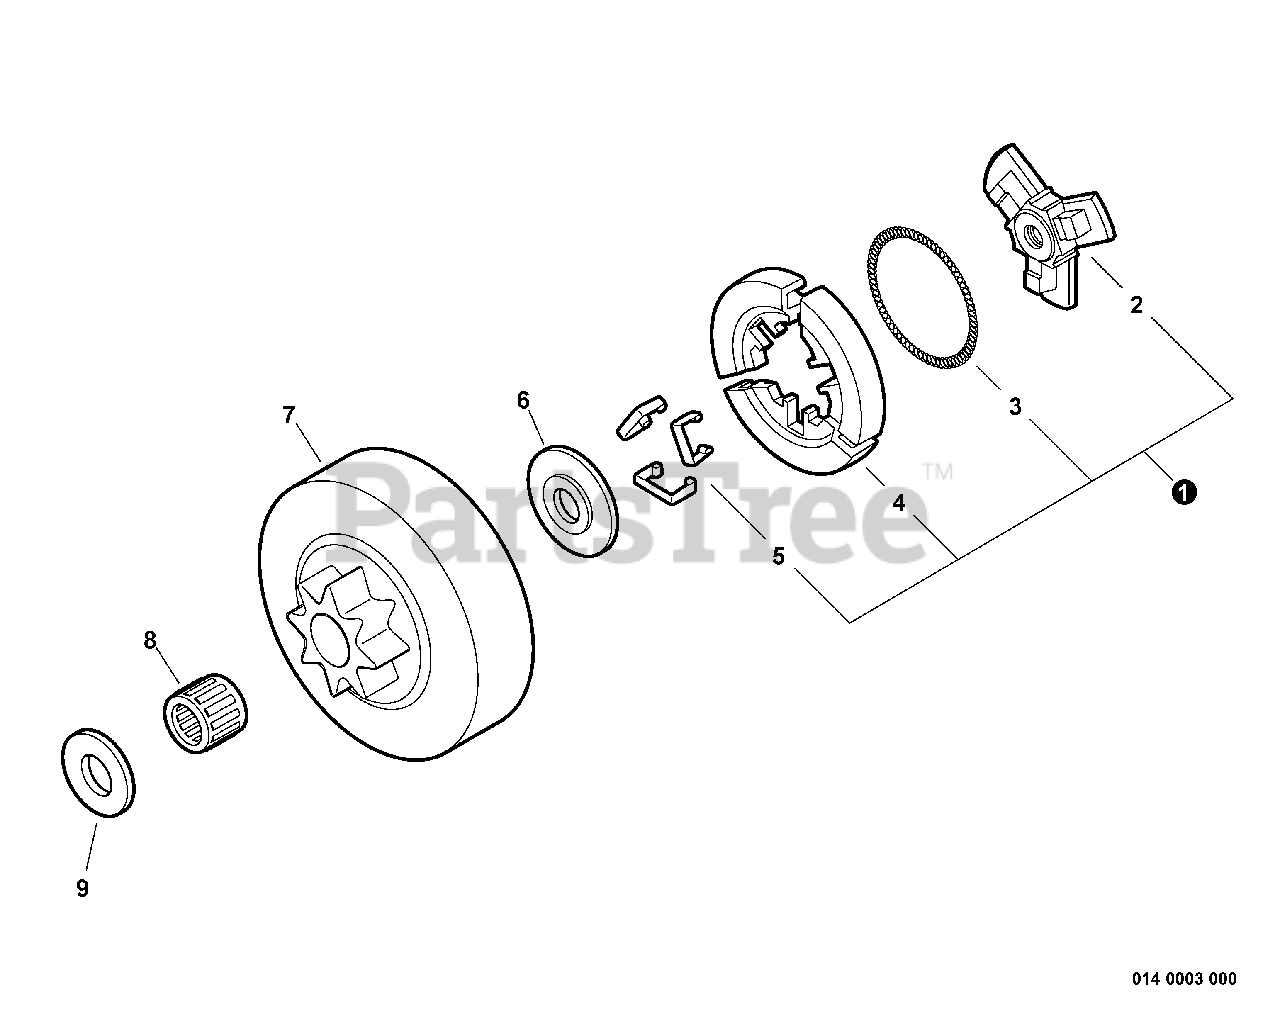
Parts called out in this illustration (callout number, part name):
1	CLUTCH ASSY
2	HUB, CLUTCH
3	SPRING, CLUTCH
4	CLUTCH SHOE SET
5	CLIP, SPRING
6	PLATE, CLUTCH
7	DRUM, CLUTCH
8	BEARING, NEEDLE
